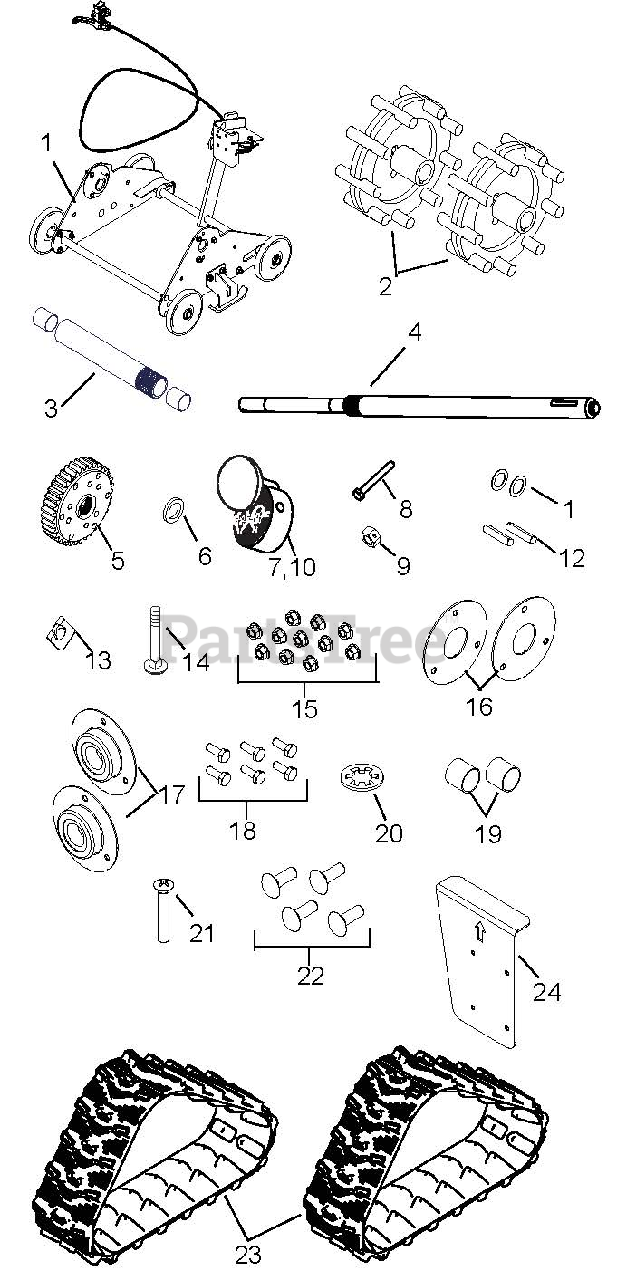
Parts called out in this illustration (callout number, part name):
1	Ariens N/A
2	WHEEL, DRIVE-TRACK
3	AXLE, SHORT-TRACK W/BUSHINGS
4	AXLE, LONG-TRACK DIFFERENTIAL
5	DIFFERENTIAL, AXLE LOCK
6	WSHR-FL-NY 1.38X2.00X.25
7	HUB, LOCKOUT-ASSEMBLY
8	@BLT-HEX .25-20X2.00 GR5 YWZC
9	@NUT-LK-CTR .25-20 YWZC
10	DIFFERENTIAL LOCK DECAL
11	WSHR-FL-STL 1.010X1.505X.062YZ
12	KEY-RECT .25X.188X1.00
13	CLIP, SNAP .625 DIA
14	BLT-RDHDXLSQNK.25-20X1.25 G5ZC
15	@NUT-LK-TOP-FLG .25-20 YWZC
16	PLATE, BEARING SPACER
17	BRG-FLG 1.003/1.000 3 BOLT
18	@BLT-HEX .25-20X.75 GR5 YWZC
19	BSHG-SLV, 1.012X1.125X1.00
20	WSHR-LK-INT .250 TH TYA
21	SCR-MCH .25-20X1.50 OVAL HD
22	@BLT-RDHDSQNK .25-20X.75 G5YZ
23	TRACK, RUBBER
24	DRILL TEMPLATE
